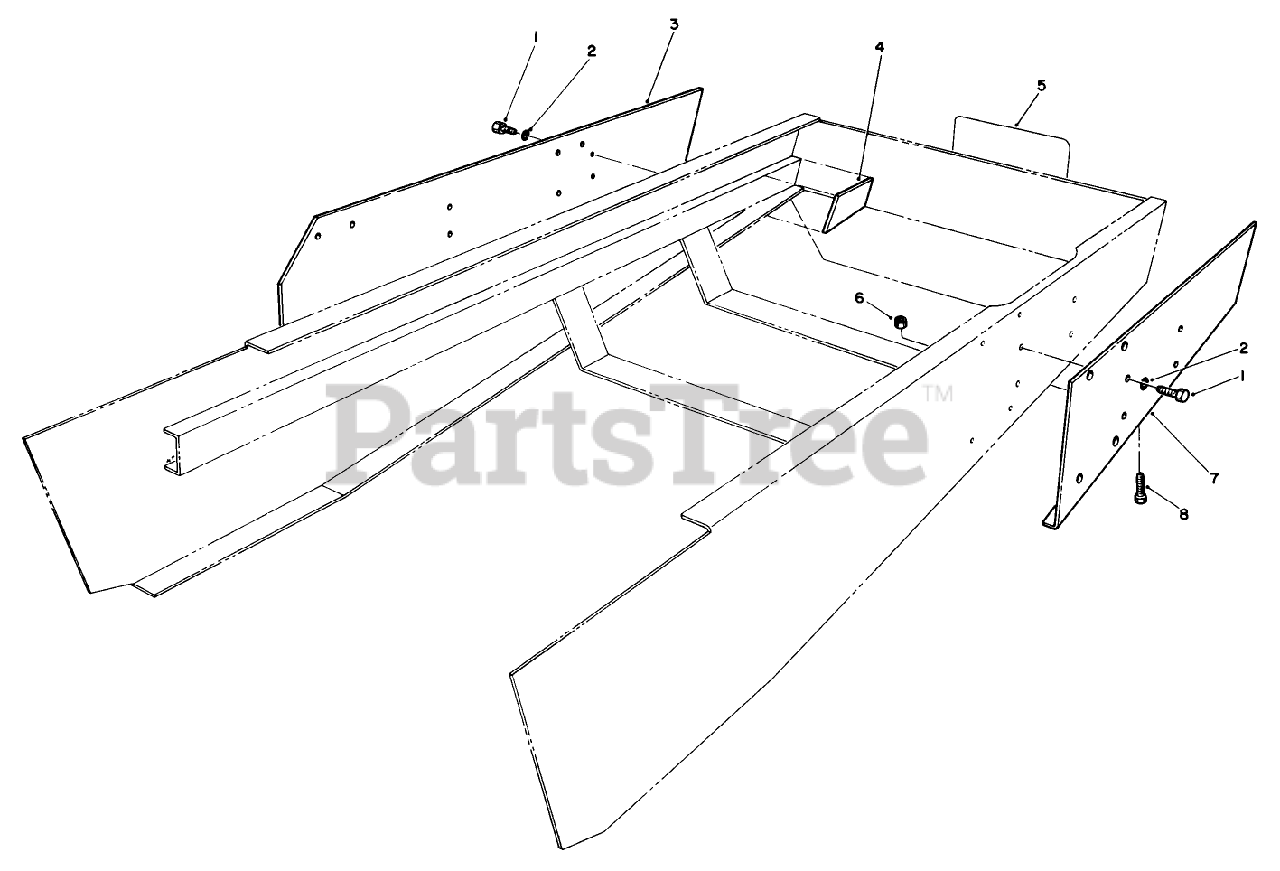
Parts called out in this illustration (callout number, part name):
1	SCREW-HH
2	WASHER-LOCK
3	Plate-R.H.
4	Plate
5	Decal-Toro
6	NUT-LOCK, NI
7	Plate-L.H.
8	SCREW-HH
